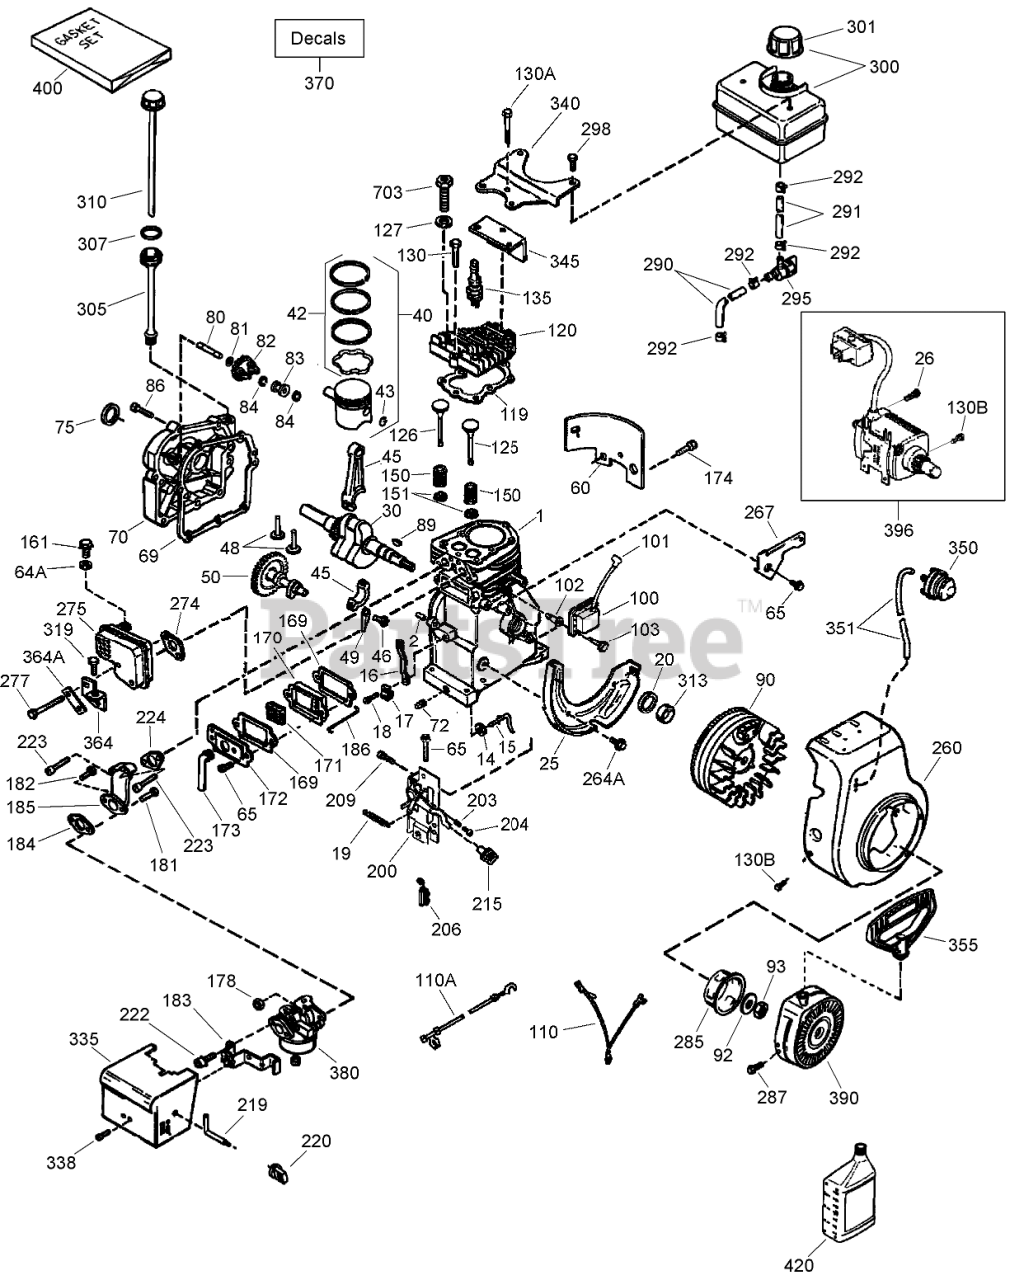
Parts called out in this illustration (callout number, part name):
1	Cylinder ASM (Includes 2, 20, 72, 125)
2	Pin-Dowel
14	Washer-Flat
15	Rod-Governor
16	Chute Idler Arm ASM (w/Bushings)
17	Clamp-Lever, Governor
18	Screw (T-15, 8-32 x 19/64)
19	Spring-Extension
20	Seal-Oil
25	Baffle-Blower Housing (Includes 262)
26	Screw (1/4-20x19/32)
30	Crankshaft ASM
40	Piston, Pin and Ring Set (STD) (Includes 41, 42, 43)
40	Piston, Pin and Ring Set (.020 O S)
40	Piston, Pin and Ring Set (.010 O S) (Includes 41, 42, 43)
42	Ring Set (.010 O S)
42	Ring Set (STD)
42	Ring Set (.020 O S)
43	Ring-Retaining, Piston Pin
45	Connecting Rod ASM (Includes 46, 49)
46	Bolt-Rod, Connecting
48	Lifter-Valve
49	Dipper-Oil
50	Camshaft
60	Extension-Blower
64A	Washer
65	Screw (10-24 x 9/16)
69	Gasket-Cover, Cylinder
70	Cover-Cylinder (Includes 75 - 80)
72	Plug-Drain, Oil (SQH 1/4-18)
75	Seal-Oil
80	Shaft-Governor
81	Washer-Flat
82	Governor Gear ASM (Includes 81)
83	Spool-Governor
84	Ring-Retaining
86	Screw (1/4-20 x 1-1/4)
89	Key-Flywheel
90	Flywheel (w/Ring Gear)
92	Washer-Belleville
93	Nut-Flywheel
100	Ignition-State, Solid
101	Cover-Spark Plug
102	Stud-Mounting, Solid State
103	Screw (T-15, 10-24 x 15/16)
110	Wire-Ground
110A	Wire-Ground (Green, 5.5)
119	Gasket-Head, Cylinder
120	Head-Cylinder (Includes 130A)
125	Valve-Exhaust (STD) (Includes 151)
125	Valve-Exhaust (1/32 O S) (Includes 151)
126	Valve-Intake (STD) (Includes 151)
126	Valve-Intake (1/32 O S) (Includes 151)
127	Washer-Flat
130	Screw (5/16-18x1-1/2)
130A	Screw (5/16-18 X 2)
130B	Screw (1/4-20 x 1/2)
135	Spark Plug-Resistor (R J19 L M)
150	Spring-Valve
151	Cap-Valve, Spring
161	Screw
169	Gasket-Cover, Valve
